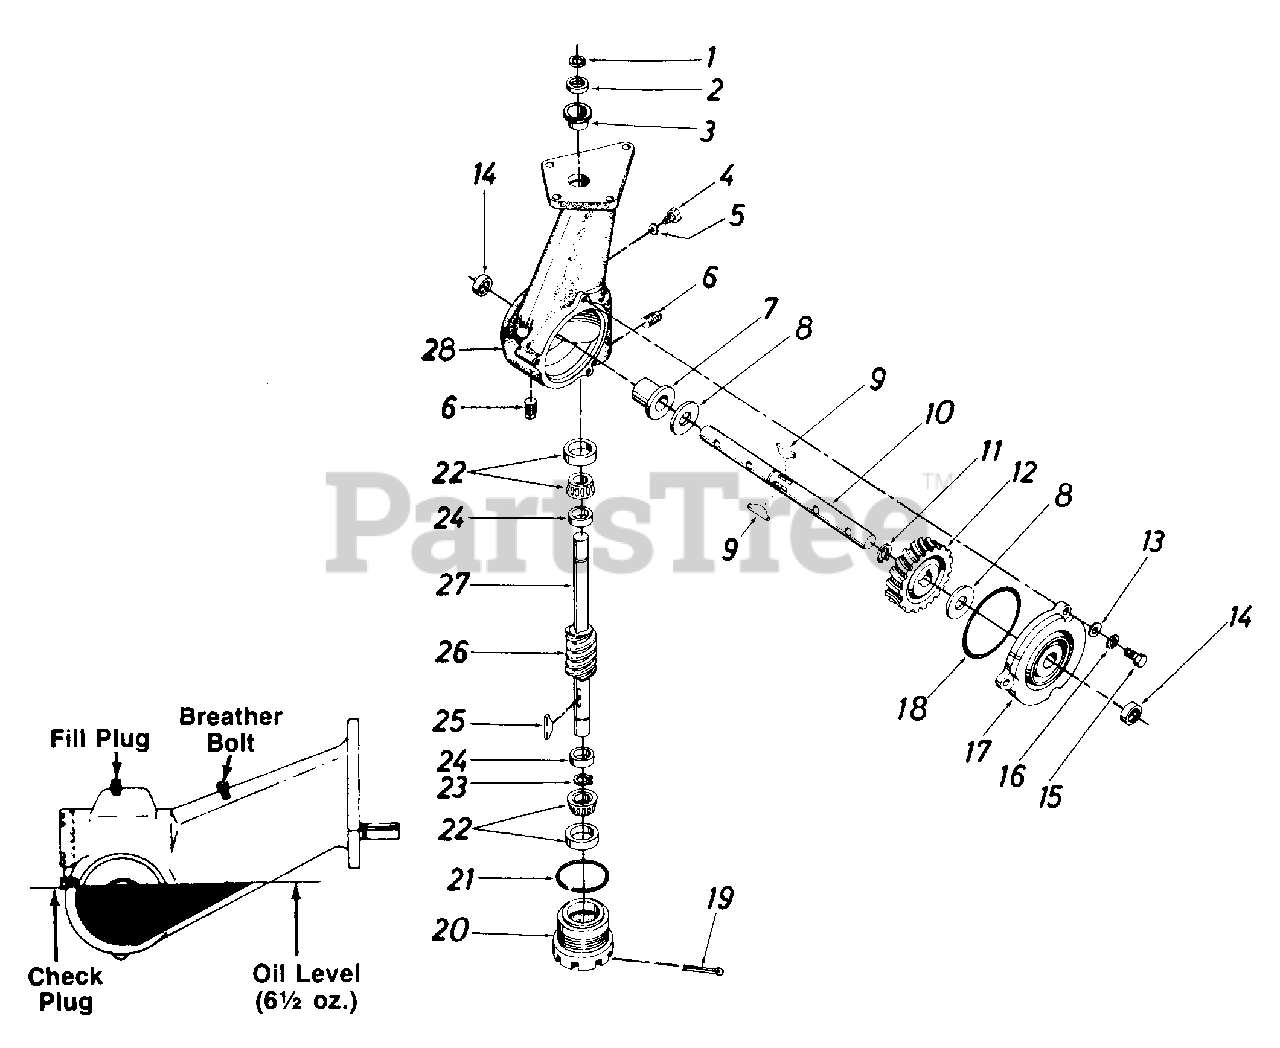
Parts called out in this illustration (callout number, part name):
1	Snap Ring .75" Dia. Shaft
2	Oil Seal .75" Dia. Shaft
3	Sleeve Brg. .752" x .878" x 1 .O"
4	Hex Wash. Self-Tap Scr.
5	External L-Wash. 114" I.D.
6	Sq. Hd. Pipe Plug 3/8" Thd.
7	Flange Brg. 1.0" I.D.
8	Fl-Wash. 1.0" x 1.62" x .095"
9	#91 Woodruff Key 1/4 x 3/4" Dia.
10	Tine Shaft 1.0" Dia.
11	Snap Ring-1.0" Dia. Shaft
12	Worm Wheel
13	L-Wash. 5/16" I.D.
14	Oil Seal Double Lip 1.0" Shaft
15	Hex Scr. 5/16-18 x .88" Lg. (Plastic Insert)
16	Wash.-Flat Toothed
17	Bearing Cap with Bearing
18	O-Ring 3.62" x 3.88"
19	Cotter Pin 1/8" Dia. x .75"
20	Bearing Adjustment Cap
21	O-Ring 2.12" x 2.28"
22	Roller Bearing Ass'y. .75 I.D.
23	Snap Ring-.75" Dia. Shaft
24	Spacer .755 I.D. x 1.265 O.D.
25	#9 Hi-Pro Key 3/16 x .75" Dia.
27	Worm Shaft
28	Transmission Case
